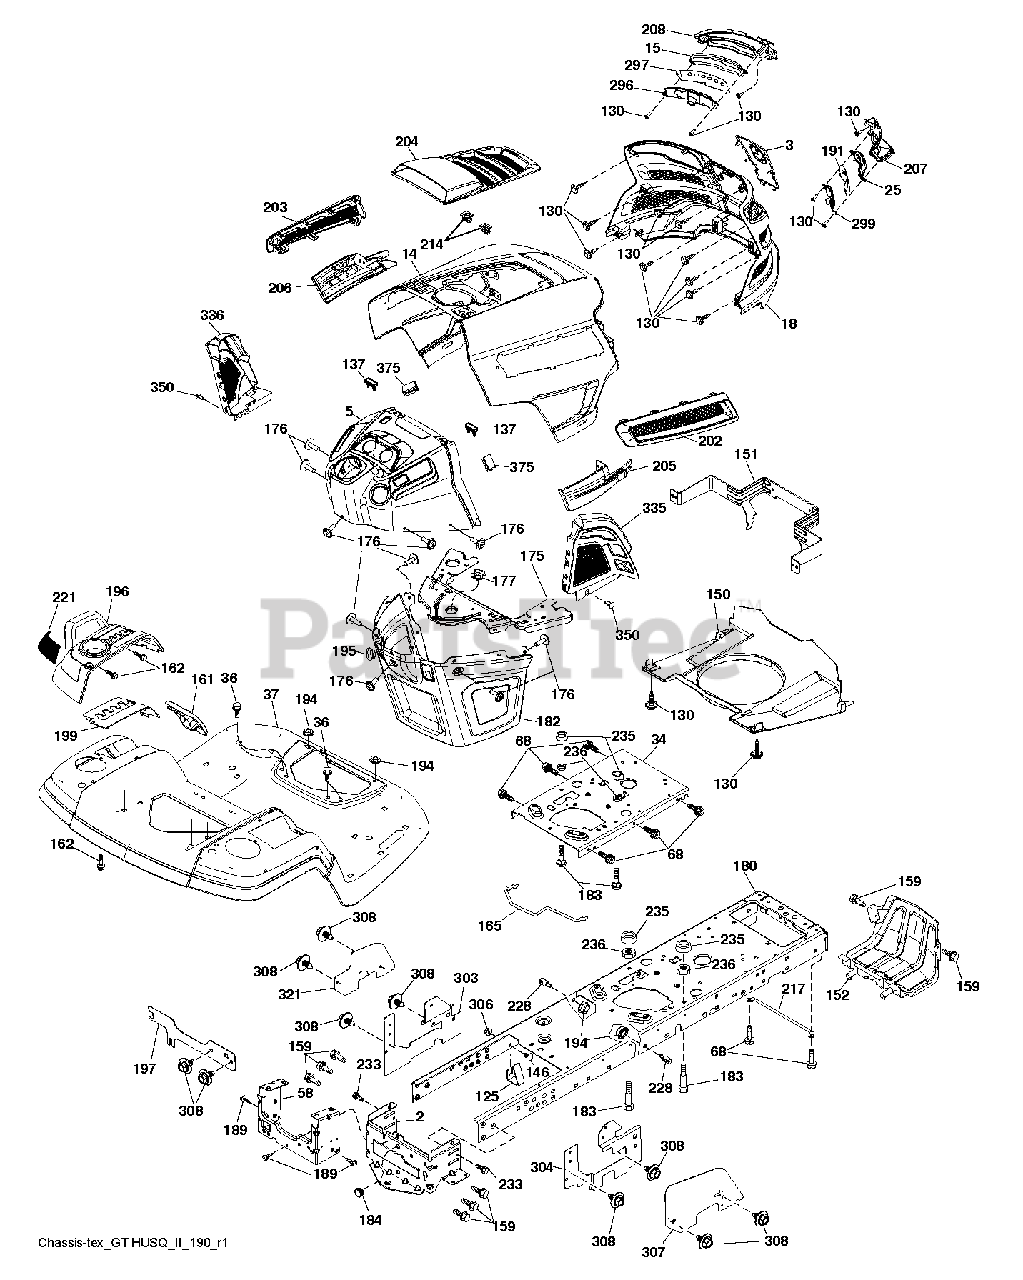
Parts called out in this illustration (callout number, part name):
2	DRAWBAR.LOWER.2PC.18/22
3	APPLIQUE.SUBASM.GT.HUSQ.II
5	GT2.DASH.UPPER.W/BUMPERS
14	HOOD.ASM.HUSQVARNA.GT.TEX.ORAN
15	LED LIGHT.LH
18	GRILLE.SUBSTRATE.2011.
25	LENS.RH
34	PLATE.ENGINE.WELDED.CHASSIS
36	SCREW 5/16"
37	FENDER.PNT.TX.GT.CH/FW/DL.HUSQ
58	DRAWBAR.UPPER.2PC,LRG.FENDER
68	SCREW LT
125	CLIP.FUEL.LINE
130	SCREW.#10 X 0.750.BOS
137	BUMPER DASH
146	BOLT.RDHD.SHT.SQNK.3/8-16X5/8
150	AIR.DUCT.GTV.BLACK
151	BRACKET.PIVOT.HOOD.GT.HUSQ.II
152	SHIELD.BROWNING.PNT.GT.V2
159	SCREW, 3/8-16X3/4
161	CONSOLE.WINDOW.FUEL.HUSQ.GT
162	SCREW.HI-LO.CONSOLE
165	SUPPORT.TANK.REAR.B/TE
175	PLATE.CROSSMEMBER.HUSQ
176	SCREW.#10-24X5/8.RN.QU
177	BUSHING, STEERING
180	CHASSIS.TEX.BOLTED
182	DASH.LOWER.COMMON.12V.ADAPTOR
183	BOLT.5/16-18X1-1/4 FULL THD
184	PLUG.DEMO.625
189	SCREW
191	INSERT INFLECT.RH
194	NUT LOCK HEX FLANGE 5/16-18
195	PLUG.HOLE.DASH.LOWER.12V.BLK
196	SUBASM.CONSOLE.HUSQ.GT.DECKLFT
197	SHIELD.DRWBAR.LT.RTANK.431
199	PLATE.DECK.LIFT.HUSQVARNA.GT
202	VENT.SIDE.RH.GT.HUSQ.II.
203	VENT.SIDE.LH.GT.HUSQ.II.498
204	VENT.TOP.HUSQ.GT2
205	SIDE.TRIM.RH.GT.HUSQ.II
206	SIDE.TRIM.LH.GT.HUSQ.II.GRAY
207	LIGHT.BEZEL. RH
208	LIGHT.BEZEL.LH
214	CLIP.RETAINER.TINNER.
217	ROD.PIVOT.HOOD
221	REFLECTOR.LH.TEX GT HU
228	STUD.FASTNER.W/ANTI-ROTATE
233	BOLT.SHOULDER
235	SPACER FENDER
236	NUT.CENTERLOCK.5/16-
296	LED LIGHT.LH
297	INSERT REFECT LH
299	LED LIGHT.RH
303	SHIELD.LOWER.LH/LT/GT/BLK.EDIP
304	SHIELD.RH.LOW.LTGT.NO
306	NUT LOCK FLG 3/8-16 UNC
307	SHIELD.UPPER.RH.GT
308	BOLT, 5/16-18 X 1 3/4
321	SHIELD.UPPER.LH.GT
335	COVER.LOWER.DASH.RH.BLACK
336	COVER-LH.LOWER.DASH.GT2.BLACK
350	CLIP.X-MAS.TREE
375	BUMPER CLIP-ON. DASH 1"
